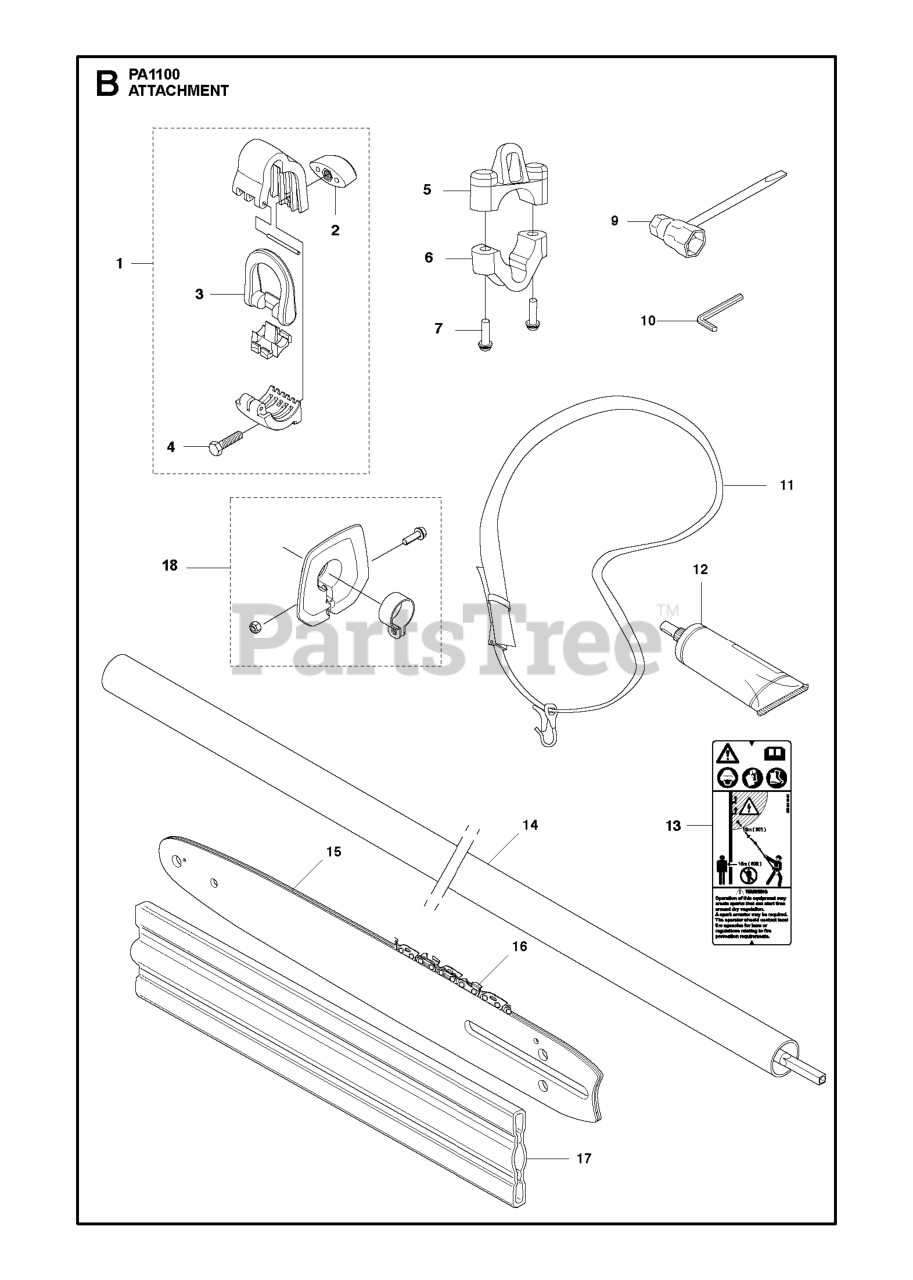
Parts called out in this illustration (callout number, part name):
1	HANGING BRACKET
4	SCREW M6S 5X20
5	CLAMP HARNESS UPPER
6	CLAMP HARNESS LOWER
9	COMBI TOOL
11	Harness-w/o warning
13	DECAL WARNING SPARK ARRESTOR
15	12" BAR, 1/4, .050 A318
15	12" DOUBLE GUARD BAR
15	BAR 1/4" A318 10" 58DL
16	SAW CHAIN H00 58DL MICRO CHISE
16	SAW CHAIN H00 64DL MICRO CHISE
16	RP12" CHN H35-44 3/8 MINI,.050
18	HANDGUARD ASSY
